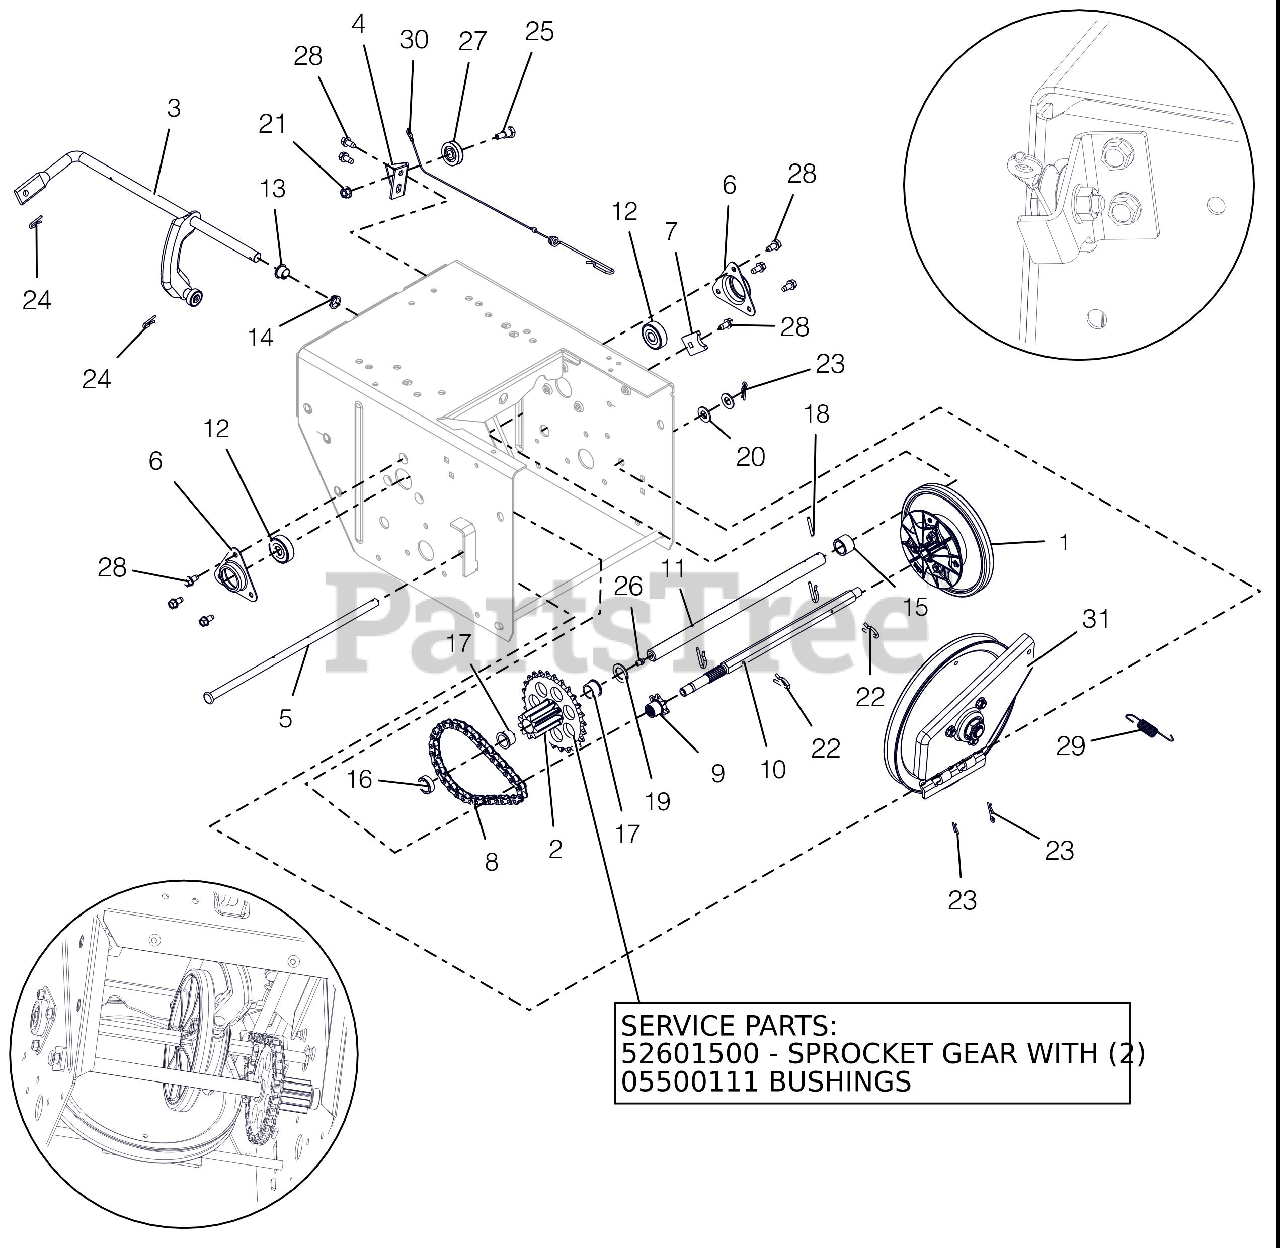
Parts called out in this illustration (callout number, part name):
1	DISC, FRICTION DRIVE-ASSEMBLY
2	PINION & SPROCKET
2	PINION & SPROCKET W/BUSHINGS
2	BSHG-FLG .625X.750X.500X.875
3	ARM, SHIFT-PRO (ASSEMBLY)
4	BRACKET, CABLE PULLEY
5	PIN, PIVOT
6	FLANGE, BEARING
7	TAB, ANTI ROTATION
8	CHAIN - #41, 32 PITCHES
9	SPROCKET, PINION 7T W/SPLINE
10	SHAFT, HEX - HEAT TREATED
11	SHAFT, PINION - HARDENED
12	BRG-BALL .437X1.375X.437
13	BUSHING, POLYLINER-.50 SPLIT
14	BUSHING, POLYLINER-.50 SNAPIN
15	SPACER, .635X.880X.611
16	BSHG-SLV, .635X.880X.305
17	BSHG-FLG .625X.750X.500X.875
18	PIN-ROLL .125X1.00
19	WSHR-FL-STL .630X1.005X.062 YZ
20	@WSHR-FL-STL.406X.812X.065 YWZ
21	@NUT-LK-TOP-FLG .25-20 YWZC
22	PIN, SPRING CLIP
23	PIN-HAIR, ENDRIES #25 YWZC
24	CLIP, SPRING
25	BOLT, SHLDR-.375X.375X.25-20
26	ZERK,FITTING .25X.125 DRIVE IN
27	PULLEY, CABLE
28	SCR-TAP .25-20X.50 HWH TR YWZ
29	SG-TENS .048X.50X2.8
30	CABLE, LOWER TRACTION,SS & PRO
31	PLATE, SWING ASSEMBLY-DEEP
